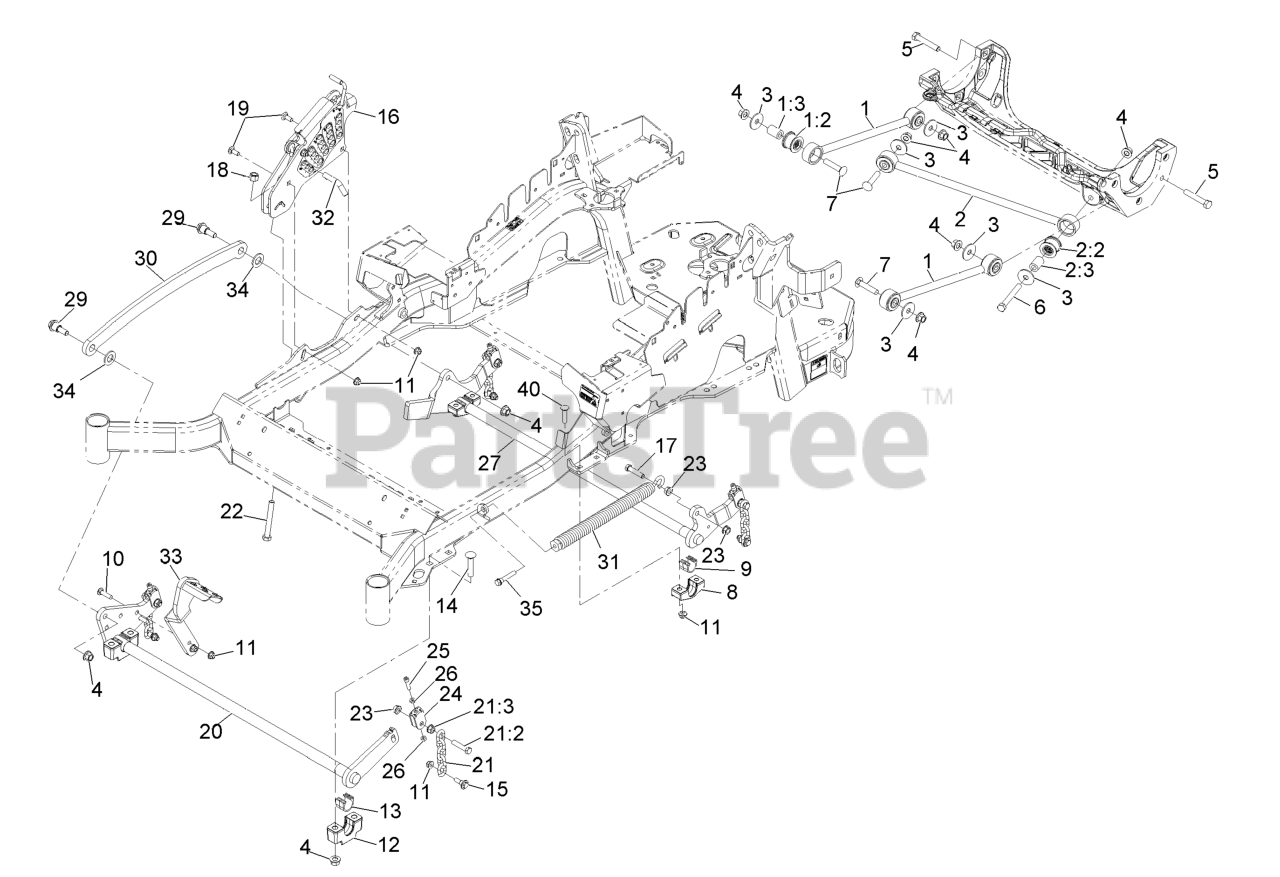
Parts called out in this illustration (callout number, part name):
1	LONG STRUT ASM
1:2	BUSHING-SUSPENSION, RUBBER
2	PANHARD ROD ASM
2:2	BUSHING-SUSPENSION, RUBBER
3	WASHER-THRUST
4	Nut-Lock 1/2-13
5	SCREW-HH
6	SCREW-HH
7	SCREW-CARR
9	BEARING-CROSS SHAFT, REAR
10	SCREW-CARR
11	NUT-HF, NI
12	SUPPORT-CROSS SHAFT, BEARING
13	BEARING-CROSS SHAFT, FRON
14	Bolt-Carriage 1/2-13 X 2 1/2 Spl Neck
15	SCREW-SHOULDER, HHF
16	HOC ASM
17	SCREW-HH
18	NUT-LOCK, NI
19	BOLT-CARR
21	DECK LIFT CHAIN ASM
21:2	SCREW-HH
22	BOLT-TAP
24	YOKE-ADJUST, DECK
25	SCREW-HSH
26	NUT-JAM
27	LIFT-DECK, REAR
29	SCREW-SHOULDER, HHF 1/2-13 X 1.12
30	LINK-LIFT, DECK
31	SPRING-EXTENSION
32	PIN-HOC
33	LEVER-FOOT
34	WASHER-FLAT
35	BOLT-SHOULDER
40	SCREW-CARR
